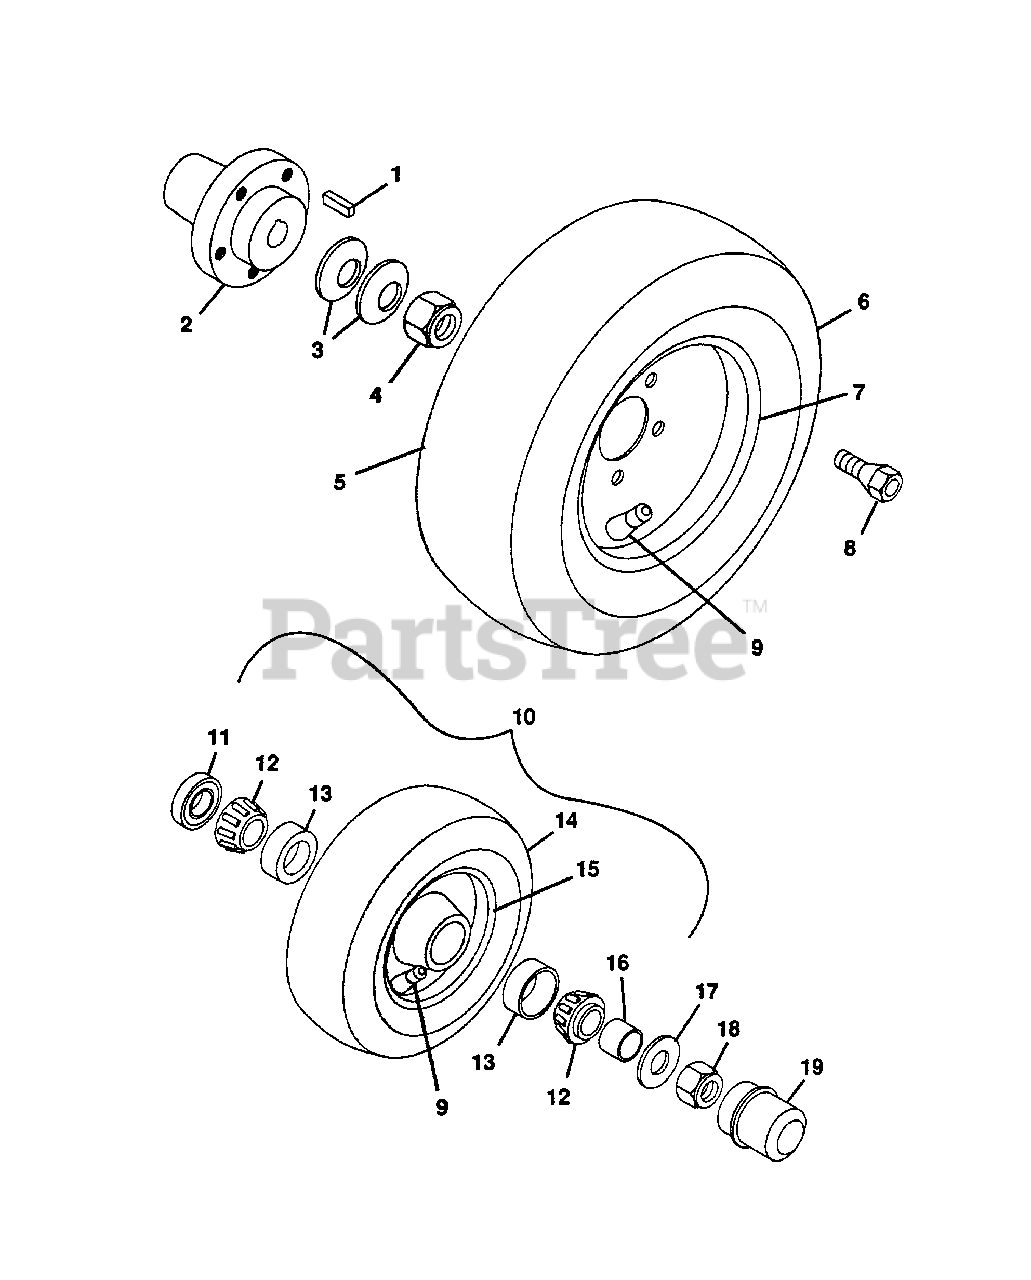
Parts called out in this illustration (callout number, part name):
1	Key, Square .312x2.25
2	Hub, Wheel
3	Spring, Belleville
4	Nut, Lock 1-14
5	Assembly, Wheel 23x8.50-12
6	Tire, Rear 23x8.50-12
7	Weldment, Rim Rear
8	Bolt, Hub 7/16-20x.75 Special
9	Assembly, Valve Stem
10	Assembly, Front Wheel 16x6.50-8
11	Seal, Oil
12	Bearing, Cone LM 11949
13	Bearing, Cup LM 11910
14	Tire, Front 16x6.50-8
15	Weldment, Rim Front
16	Spacer
17	Washer, Flat .656x1.312x.095
18	Nut, Lock 5/8-11
19	Cap, Dust
